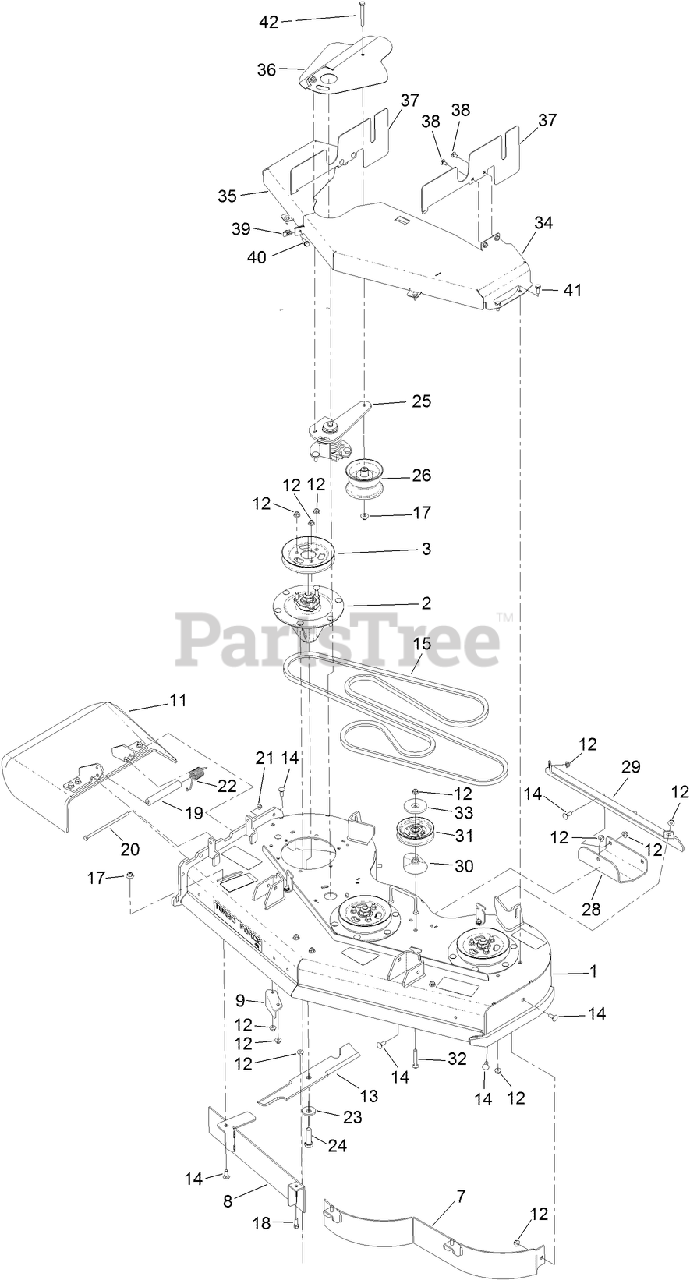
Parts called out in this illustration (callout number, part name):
1	DECK ASM
2	SPINDLE ASM
3	PULLEY
7	48 INCH BAFFLE ASM
9	BAFFLE-DISCHARGE
11	DEFLECTOR ASM
12	NUT-HF, NI
13	BLADE-16.5 INCH (HIGH FLOW)
14	BOLT-CARR
15	BELT-V
17	NUT-FLANGE, NI
18	SCREW-HWH
19	SPACER
20	SCREW-HH
21	NUT-HF, NI
22	SPRING-TORSION
23	Washer-Blade Bolt, Heavy
24	SCREW-BLADE
25	TORSION IDLER ASM
26	PULLEY-IDLER
29	BRACKET-SKID
30	SPACER-PULLEY
31	IDLER-PULLEY, FLAT
32	SCREW-CARR
33	SHIELD-DUST
34	COVER-BELT, LH (CE)
35	COVER-BELT, RH (CE)
36	COVER-IDLER (CE)
37	COVER-SIDE, LH (CE)
38	SCREW-CARR
39	NUT-U
40	SCREW-HHF
41	SCREW-HH
42	SCREW-HH
